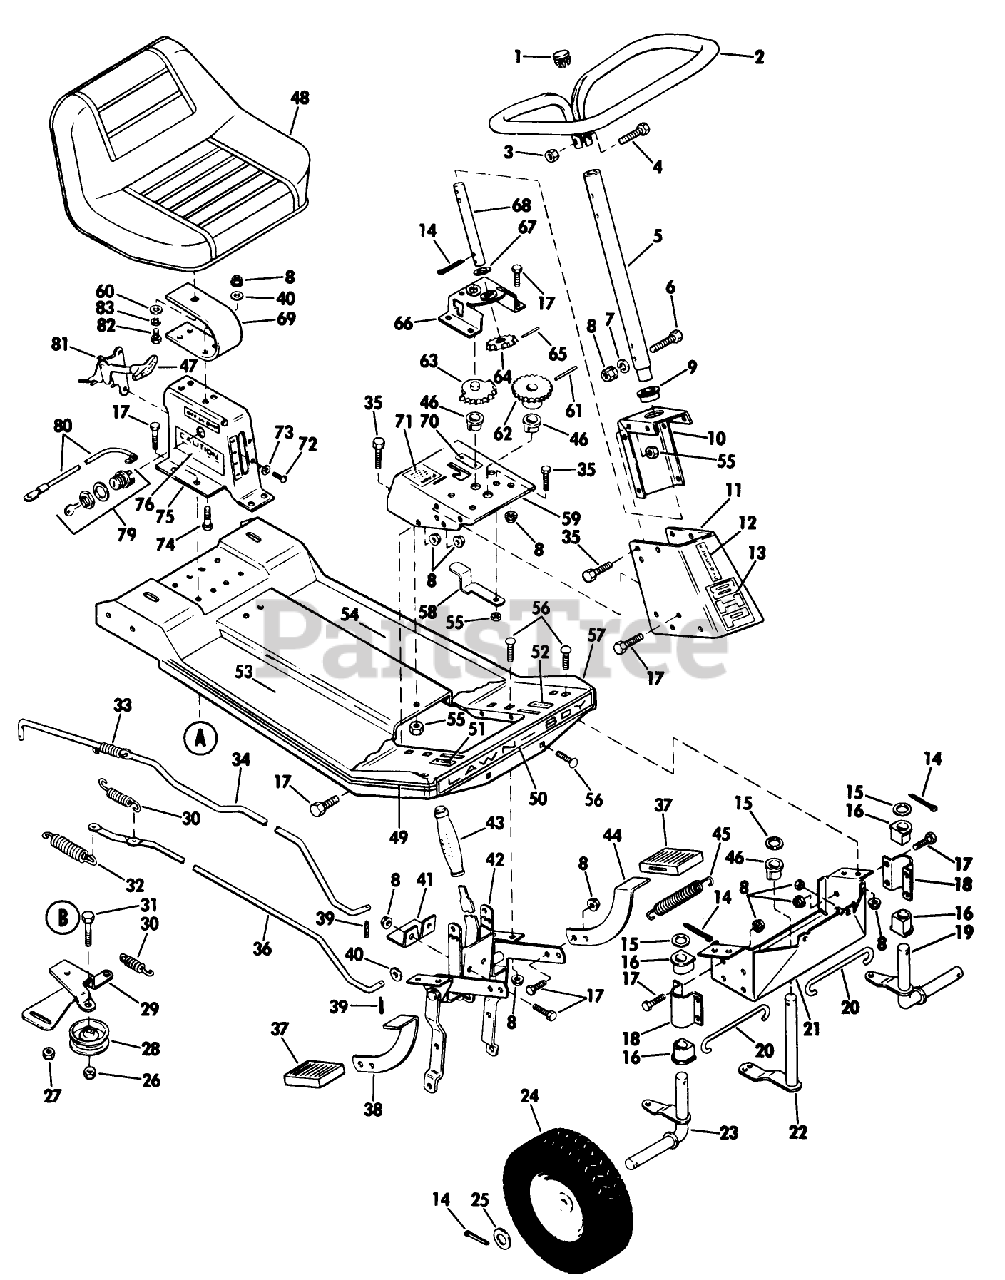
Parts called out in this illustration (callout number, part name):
3	STOP NUT
13	Spring-Clutch Rod
15	Washer-Front Axle
16	Bushing-Front Axle
19	Axle Assembly-Front L.H.
23	Axle Assembly-Front R.H.
24	Wheel and Tire Assembly-Front
25	Washer-Wheel and Tire Assembly
26	LOCKNUT
28	Pulley-Idler
29	Idler Lever
32	Spring-Clutch Rod
33	Spring-Brake Rod
37	Pad-Foot Pedal
38	Pedal-Foot R.H.
43	Grip-Handle
44	Pedal-Foot L.H.
47	Handle-Throttle Control
53	Mat-Floor-R.H.
54	Mat-Floor-L.H.
67	Washer-Thrust
72	SCREW F
73	Lockwasher
74	Screw-Seat Support
